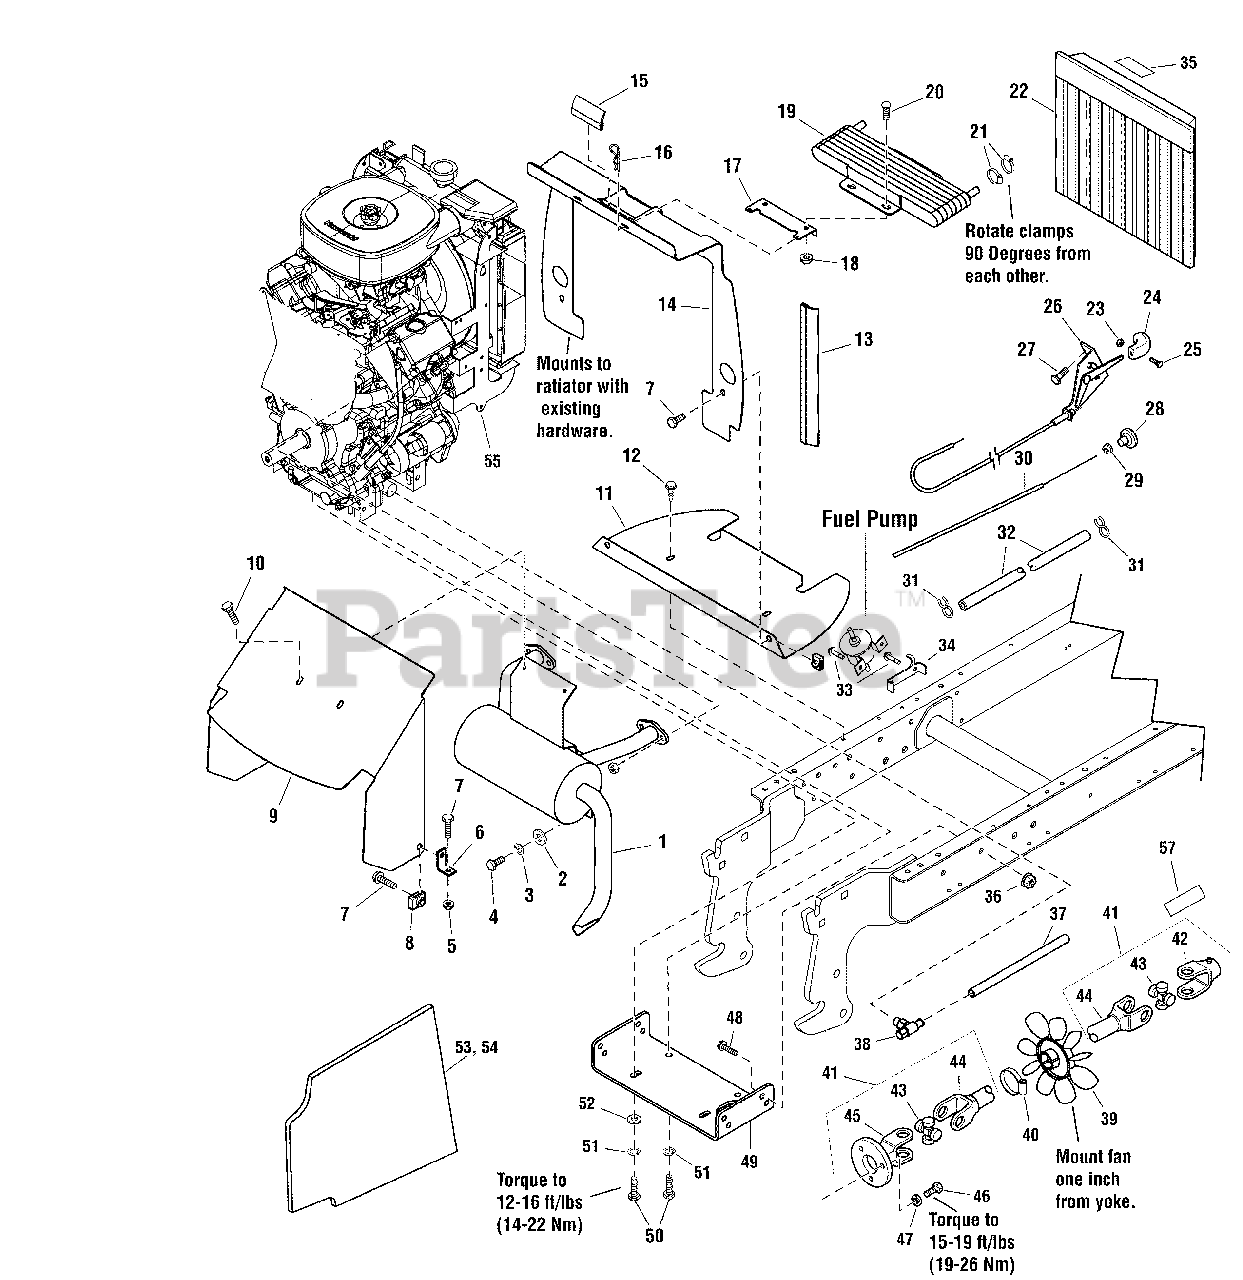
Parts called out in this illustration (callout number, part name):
2	WASHER, 5/16
3	LOCKWASHER, Spring 5/16
4	CAPSCREW, Hex Head
5	NUT, Hex KEPS 5/16-18
6	BRACKET, L.
7	SCREW, Hex Whiz Lock Flange, 5/16-18 x 3/4
8	NUT, Lug, 5/16-18
9	SHROUD, Muffler 18GA
10	SCREW, Hex Washer Head Taptite, 1/4-20 x 1/2
11	BAFFLE, Lower 18GA
12	SCREW, Hex Washer Head Taptite, 5/16-18 x 3/4
13	EDGING, 12 1/2LG
14	BAFFLE, Upper 18GA
15	EDGING, 15 1/2 LG
16	CLIP, Hair Pin
17	BRACKET, Cooler MTG 16GA
18	NUT, Hex KEPS, 1/4-20
19	COOLER ASSEMBLY, Oil
20	CARRIAGE BOLT, 1/4-20 x 3/4 G5
21	CLAMP, Hose
22	SCREEN ASSEMBLY
23	NUT, Hex Lock, 10-24
25	SCREW, Pan Head Phillips, #10-24 x 1
26	CONTROL, Throttle
27	SCREW, Hex Washer Head, #12-24 x 5/8
28	KNOB, Intermediate Thread, #10-24, 1-7/16LG
29	NUT, Hex KEPS #10-24
30	CONTROL, Choke
31	BAFFLE, Ower Kawasaki
33	SCREW, Hex Washer Head Taptite, 1/4-20 x 1-1/8
34	PLATE, Tilt
35	DECAL, Clean Radiator Legacy KAW & Diesel
36	NUT, Hex KEPS, 3/8-16
37	HOSE, Hydraulic
38	VALVE, Oil Drain
40	CLAMP, Hose
41	SHAFT ASSEMBLY, Drive
42	YOKE & FLANGE, Drive Shaft
43	CROSS & BEARING KIT, Includes Grease Fitting
44	YOKE & TUBE ASSEMBLY
45	YOKE, Drive Shaft
46	CAPSCREW, Hex Head
47	LOCKWASHER, Spring
48	SCREW, Hex Whiz Lock Flange, 3/8-16 x 1
49	BASE, Engine
50	CAPSCREW, Hex Head
51	LOCKWASHER, Spring
52	WASHER, 3/4
53	INSULATION, Foam
54	INSULATION, Foam
55	** ENGINE, 27HP Kawasaki Liquid Cooled Twin
57	TAPE, Double Sided 7/8 x 4-3/4
